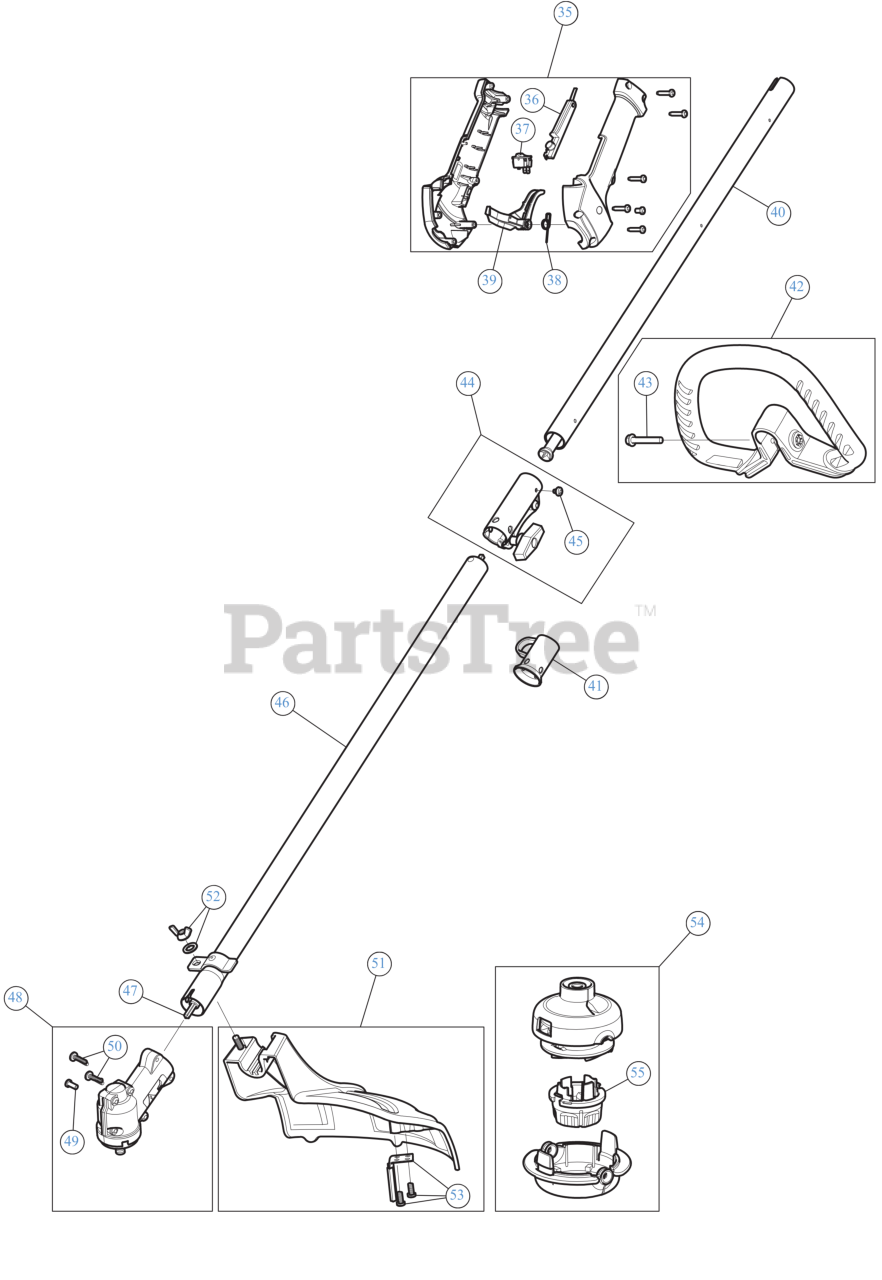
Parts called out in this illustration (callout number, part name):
35	THROTTLE GRIP ASSEMBLY
36	LEVER LOCK OUT
37	SW, MOMENTARY ON/O
38	TRIGGER SPRING
39	THROTTLE TRIGGER
40	BOOM ASSEMBLY UPR
41	HANGER
42	D-HANDLE
43	BOLT 1/4-20X1 1/2
44	SPLIT BOOM COUPLER KIT
45	SCREW, 10-32X.250 TA
46	BOOM ASSEMBLY LOWER
47	LOWER DRIVE SHAFT
48	GEARBOX LCBC
49	SCREW, 8-32 x .312 P
50	SCREW #
51	GUARD/BLADE ASM
52	BLADE GUARD MOUNTING HARDWARE
53	BLADE ASSEMBLY W/HDW
54	CUTTING HEAD ASSEMBLY
55	BUMP KNOB
